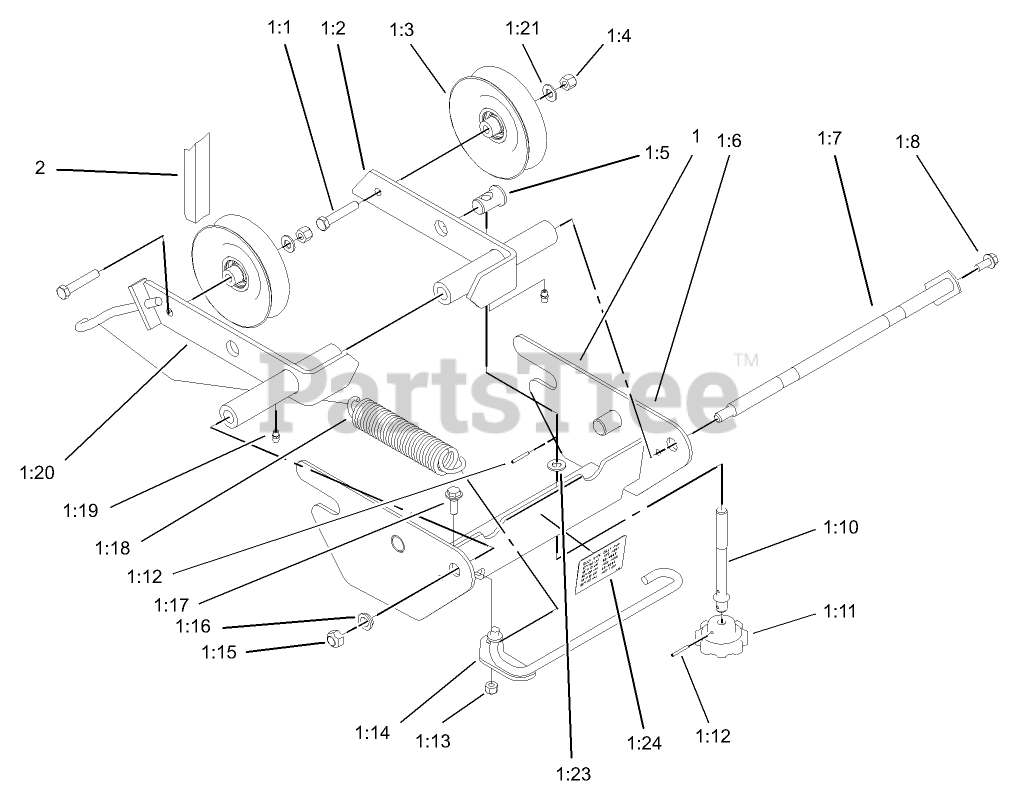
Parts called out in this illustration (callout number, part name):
1	PULLEY BOX ASM
1:1	SCREW-HH
1:2	LH TENSION BRACKET ASM
1:3	PULLEY-IDLER
1:4	NUT-LOCK, NI
1:5	FERRULE-ADJUSTER
1:6	PULLEY BOX ASM
1:7	ROD-PIVOT
1:8	SCREW-HWHTF
1:10	ROD-TENSION
1:12	PIN-ROLL
1:13	NUT-LOCK, NI
1:14	TENSIONER-IDLER
1:15	NUT-LOCK, NI
1:16	SPACER-SHOULDER
1:17	SCREW-SHOULDER
1:18	SPRING-EXTENSION
1:19	FITTING-GREASE
1:20	RH TENSION BRACKET ASM
1:21	WASHER-PLAIN
1:23	WASHER
1:24	DECAL-PULLEY BOX
2	BELT-V
